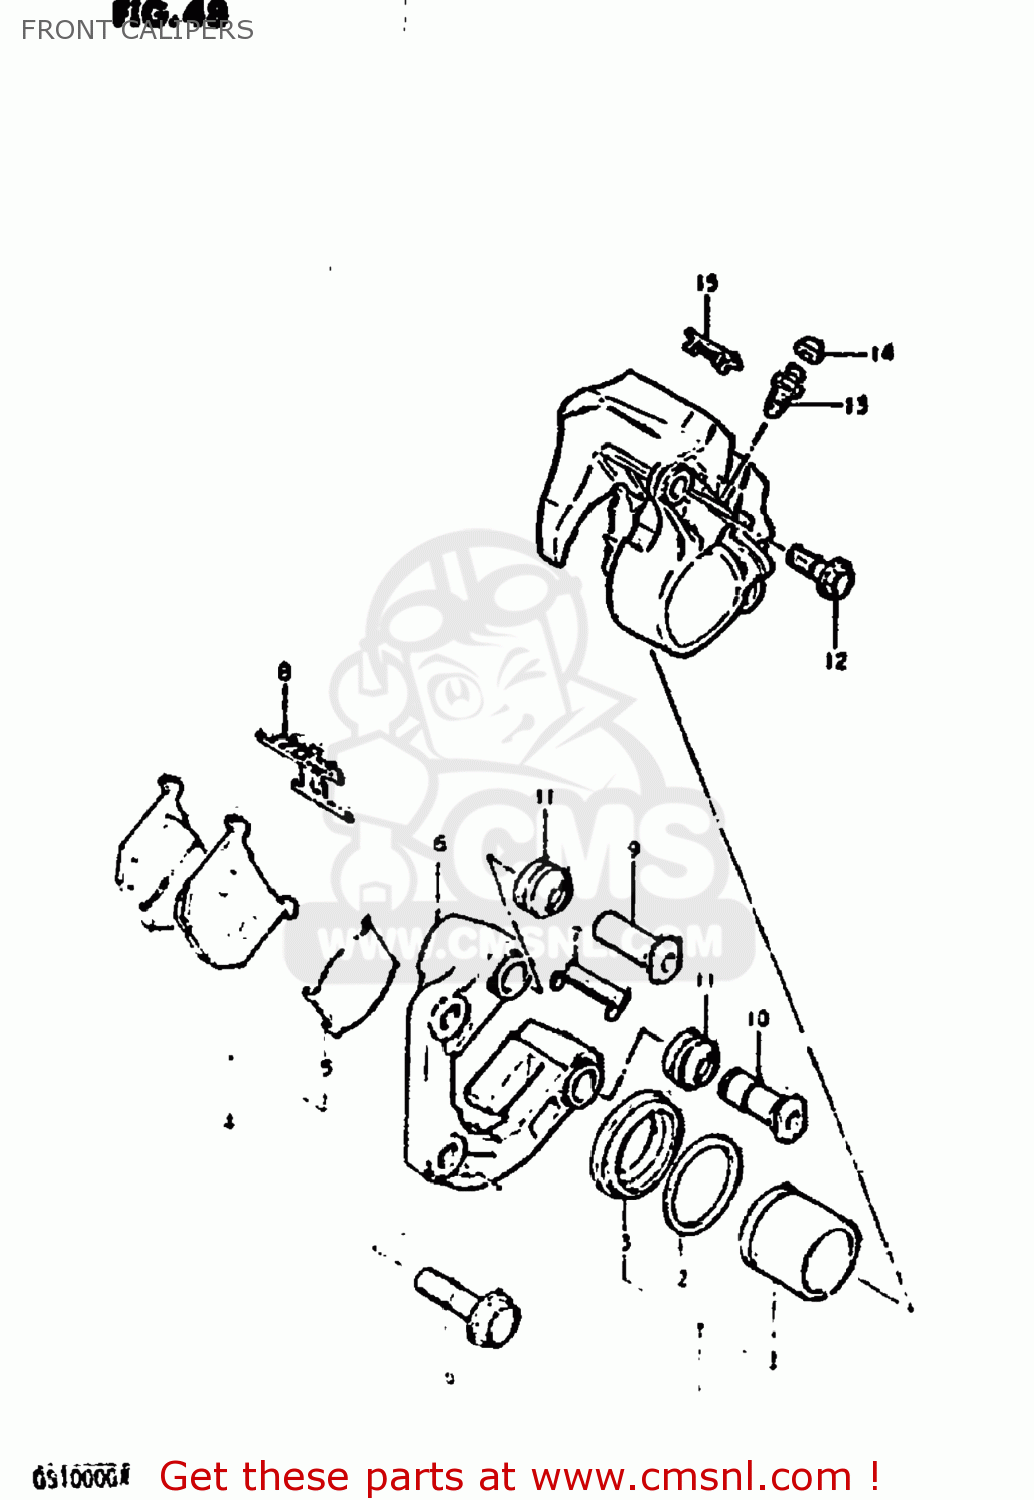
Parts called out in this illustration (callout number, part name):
0	CALIPER ASSEMBLY,FRONT,LEFT
1	PISTON SET
2	SEAL,PISTON
3	BOOT,PISTON
4	PAD SET (MCA)
5	SHIM,PAD
6	CARRIER,CALIPER,LEFT
7	GUIDE,PAD
8	SPRING,PAD
9	AXLE NO.1
10	AXLE NO.2
10A	BUSH,AXLE
11	BOOT,AXLE
12	BOLT,CALIPER HOUSING
13	BLEEDER
14	CAP,BREATHER
15	COVER,INDICATOR
16	BOLT(10X37)
